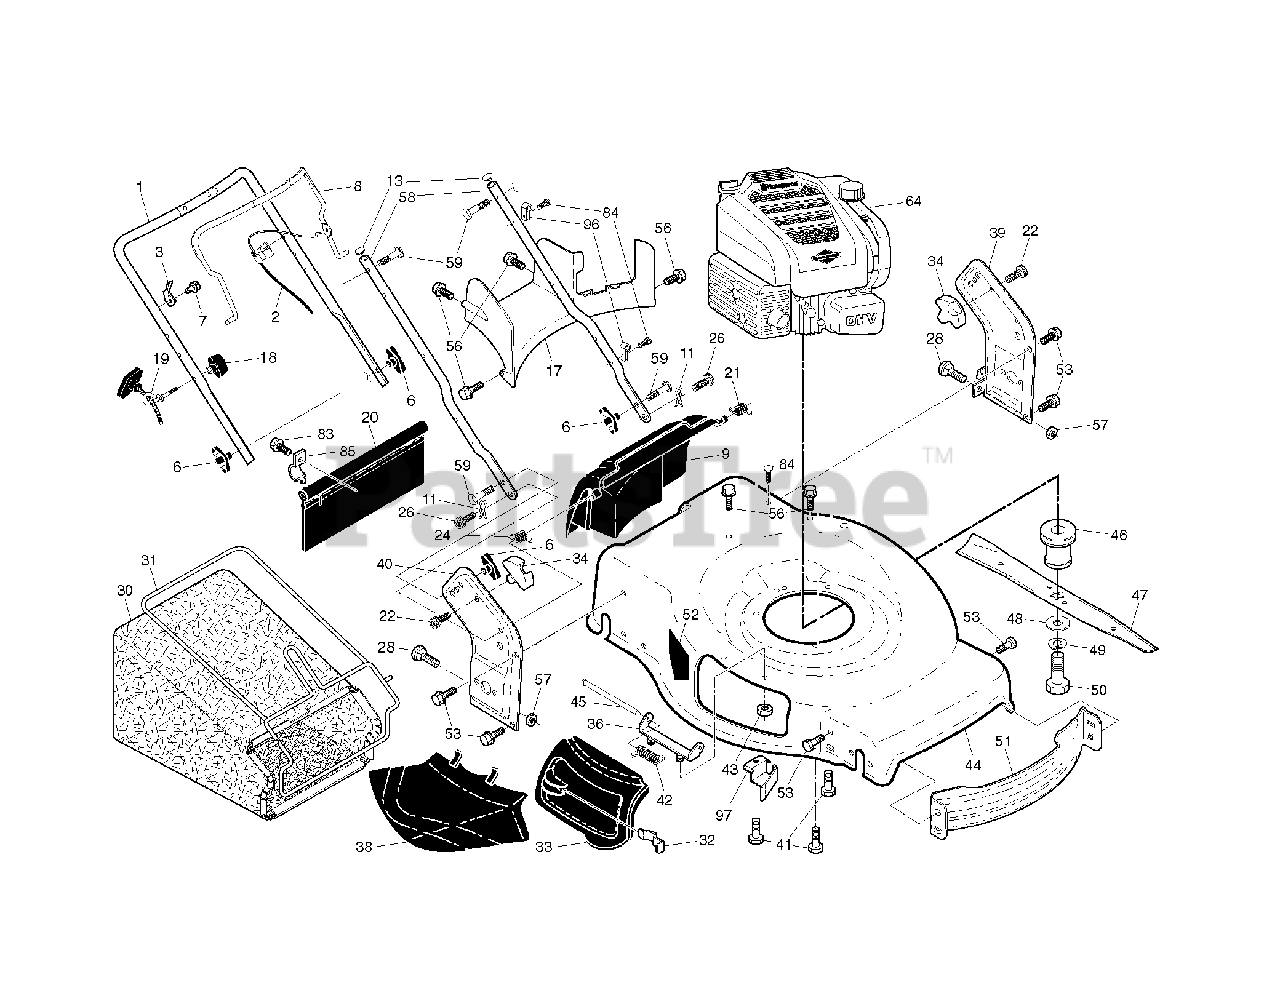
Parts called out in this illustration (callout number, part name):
1	HANDLE.UP.DSTR.EZ.FGR
2	CABLE.MZR.ZONE.CONTROL
3	BRACKET.UPSTOP.RT
8	BAIL.MZR.EZ2.DSTRT.22+.421
9	DOOR.REAR.22+GEN.RG.EBA.BLK
11	COTTER.HAIRPIN.DOOR/HANDLE.PIV
13	PLUG.PLASTIC.7/8".14-20.GAUGE
17	BAFFLE.REAR.22+RGD.AWD.PLASTIC
18	T-KNOB.NEW ROPE GUIDE
19	Rope Guide, Blk Zinc Chrom
20	SKIRT.REAR.22PLUS.RGD.LW.2012
21	SPRING.LH.GRAY
22	SCREW.PAN.HEAD.#10
24	SPRING.RH.GRAY
26	SCREW,DOOR/HANDLE.PIVOT
28	Carriage Bolt, 5/16-18 X 5/8
30	GBAG.A1640416S.BLK.PPRO.MRG.
31	Grass Bag Frame, 22+ Black
32	LATCH.DOOR.ZINC
33	DOOR.MULCH.22.BLACK.MULTI-BRAN
34	BRACKET.GRASSBAG.ATTACHING.BLK
36	BRACKET.ASM.HINGE.21.FWGD.
38	DEFLECTOR.CLIPPING.22.BLACK
39	Handle Bracket Assembly, LH 22+ Black
40	Handle Bracket Assembly, RH 22+ Black
41	BOLT 3/8-16X1-1/8
42	SPRING.TORSION
43	NUT.HEX.FLANGE.1/4
44	KIT.HSG.22+.RGD.MC.WO.BLK.TRI
45	ROD.HINGE.21
46	ADAPTER.BLADE.25MM.3MPH
47	BLADE.22PLUS
48	WASHER,HARDEN
50	SCREW, HEX HD 3/8-24 X 1-3/8
51	BAFFLE.FRONT.22.PLUS
52	DECAL.INTERNATIONL.CUTFINGER
53	BOLT.5/16HEX.WHS.HD
56	SCREW.HX.13X.750
57	NUT.FLANGE.5/16
58	HANDLE.LOWER.22+.BT.2PC.BLK
59	BOLT, HANDLE 5/16-18X1.75
83	TAPPING SCREW
84	FASTENER.PUSH.O.250X0.783
85	BRACKET.SKIRT.22+.BZP
96	CLIP.CABLE.BLK
97	BRACKET.BELT.GUIDE.22+.BZP
